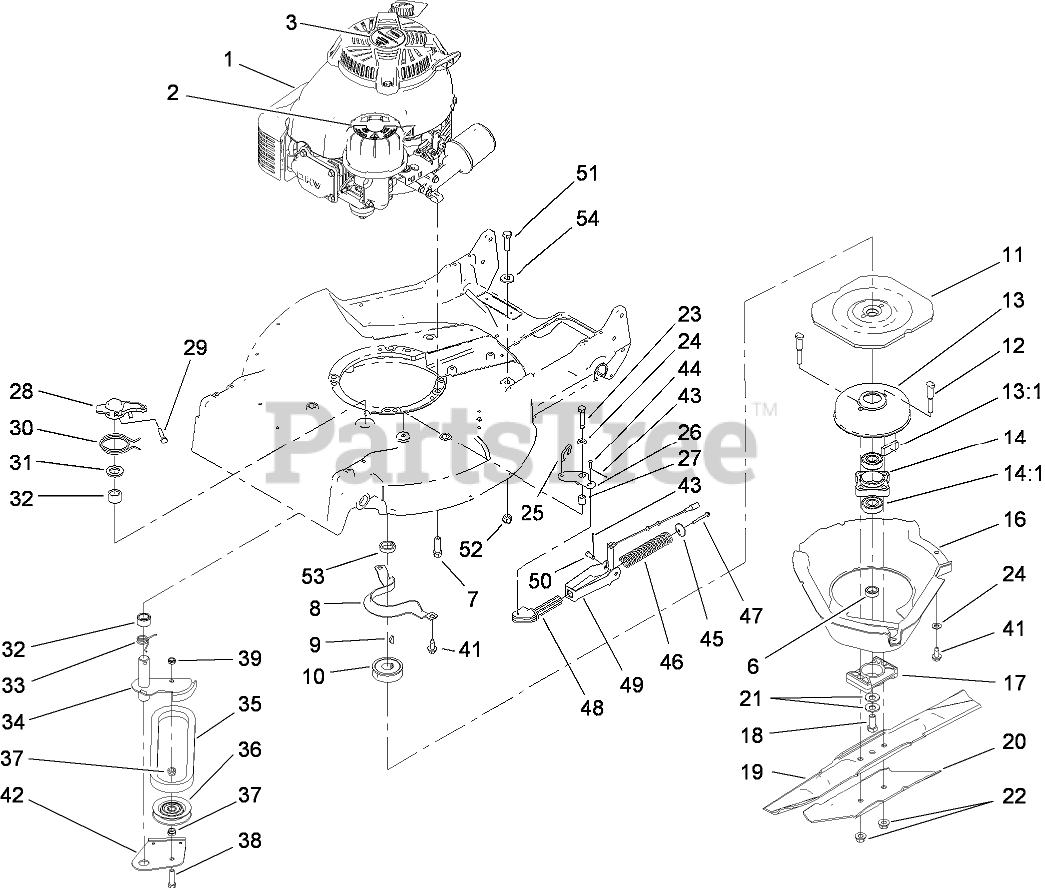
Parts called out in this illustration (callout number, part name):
1	ENGINE-KAWASAKI, FJ180V-AS30
3	DECAL
6	SPACER-SHAFT, OUTPUT
7	SCREW-TAPTITE
8	BRACKET-GUIDE, BELT
9	KEY-WOODRUFF
10	PULLEY-DRIVER
11	FLYWHEEL-BBC
12	BOLT-BLADE
13	BRAKE DRUM ASM
13:1	DAMPENER-VIBRATION
14	HUB ASM
14:1	BEARING-BALL
16	SHIELD
17	SPACER-BLADE
18	SCREW-HH
19	BLADE-21 INCH
20	STIFFENER-BLADE
21	WASHER-SPRING
22	NUT-LOCK
23	SCREW-HH
24	WASHER-PLAIN
25	LINK-CONTROL
26	BELLCRANK
27	SLEEVE-BELLCRANK
28	LEVER
29	SCREW-HH
30	SPRING-TORSION
31	WASHER
32	BEARING
33	SPRING-TORSION
34	ARM-IDLER
35	V-BELT
36	PULLEY-IDLER
37	SPACER-PULLEY, IDLER
38	SCREW-HH
39	NUT-LOCK, NI
41	SCREW-HWHTF
42	BRAKE PLATE ASM
43	PIN-COTTER
44	PIN-SPRING
45	RETAINER-SPRING
46	SPRING
47	SCREW-HWHTF
48	GUIDE-SPRING
49	BRACKET-SPRING
50	PIN-CABLE
51	SCREW-HH
52	NUT-LOCK, NI
53	SPACER-PULLEY
54	WASHER-HARDENED
